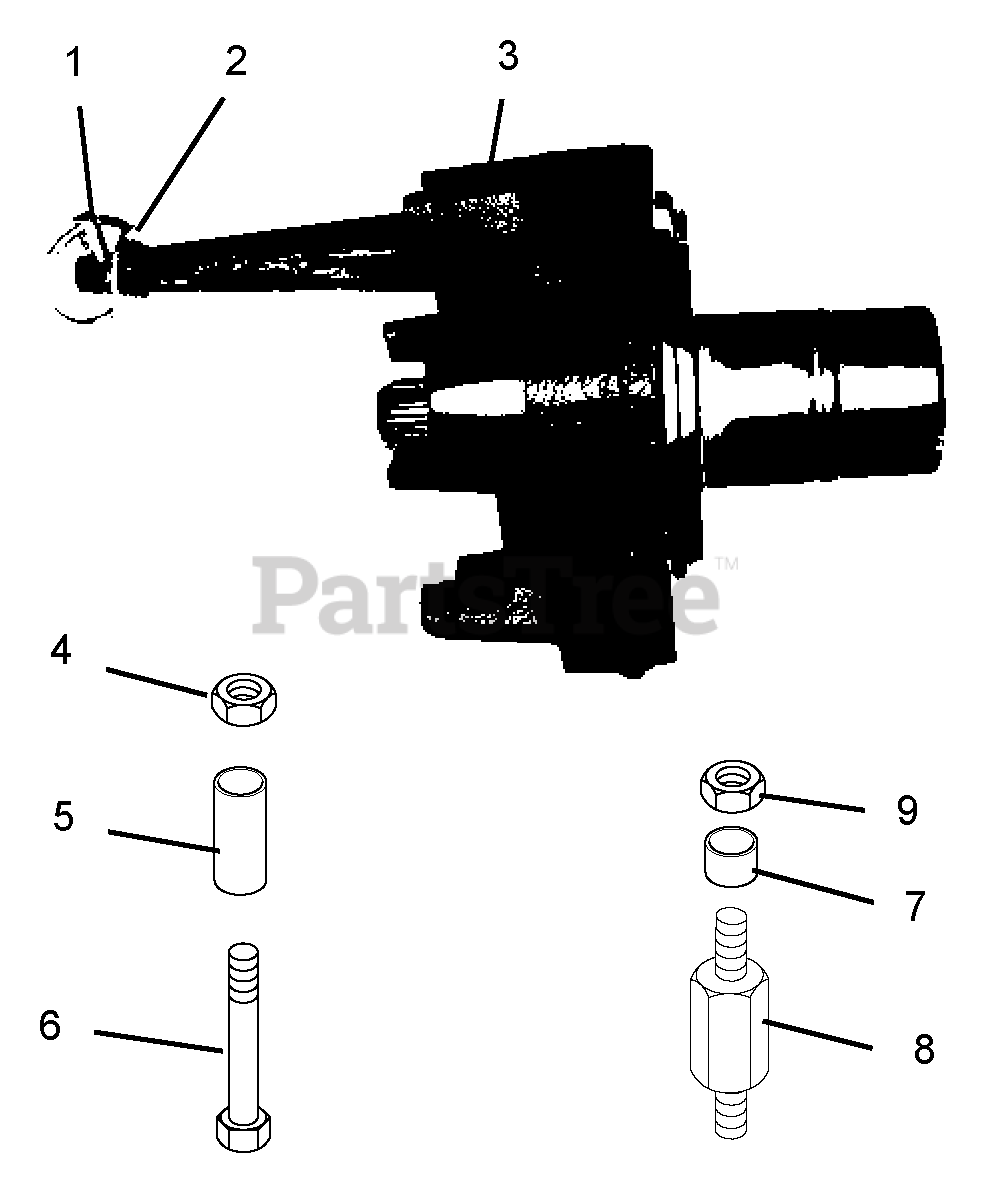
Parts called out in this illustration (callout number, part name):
1	Lynch Pin
2	3/4" Flat Washer
3	Adapter
4	1/2" Center Locknut
5	Spacer
6	1/2" x 4-1/2" Hex Bolt
7	Coupler Sleeve
8	Quick-Hitch Stud
9	1/2" Center Locknut
